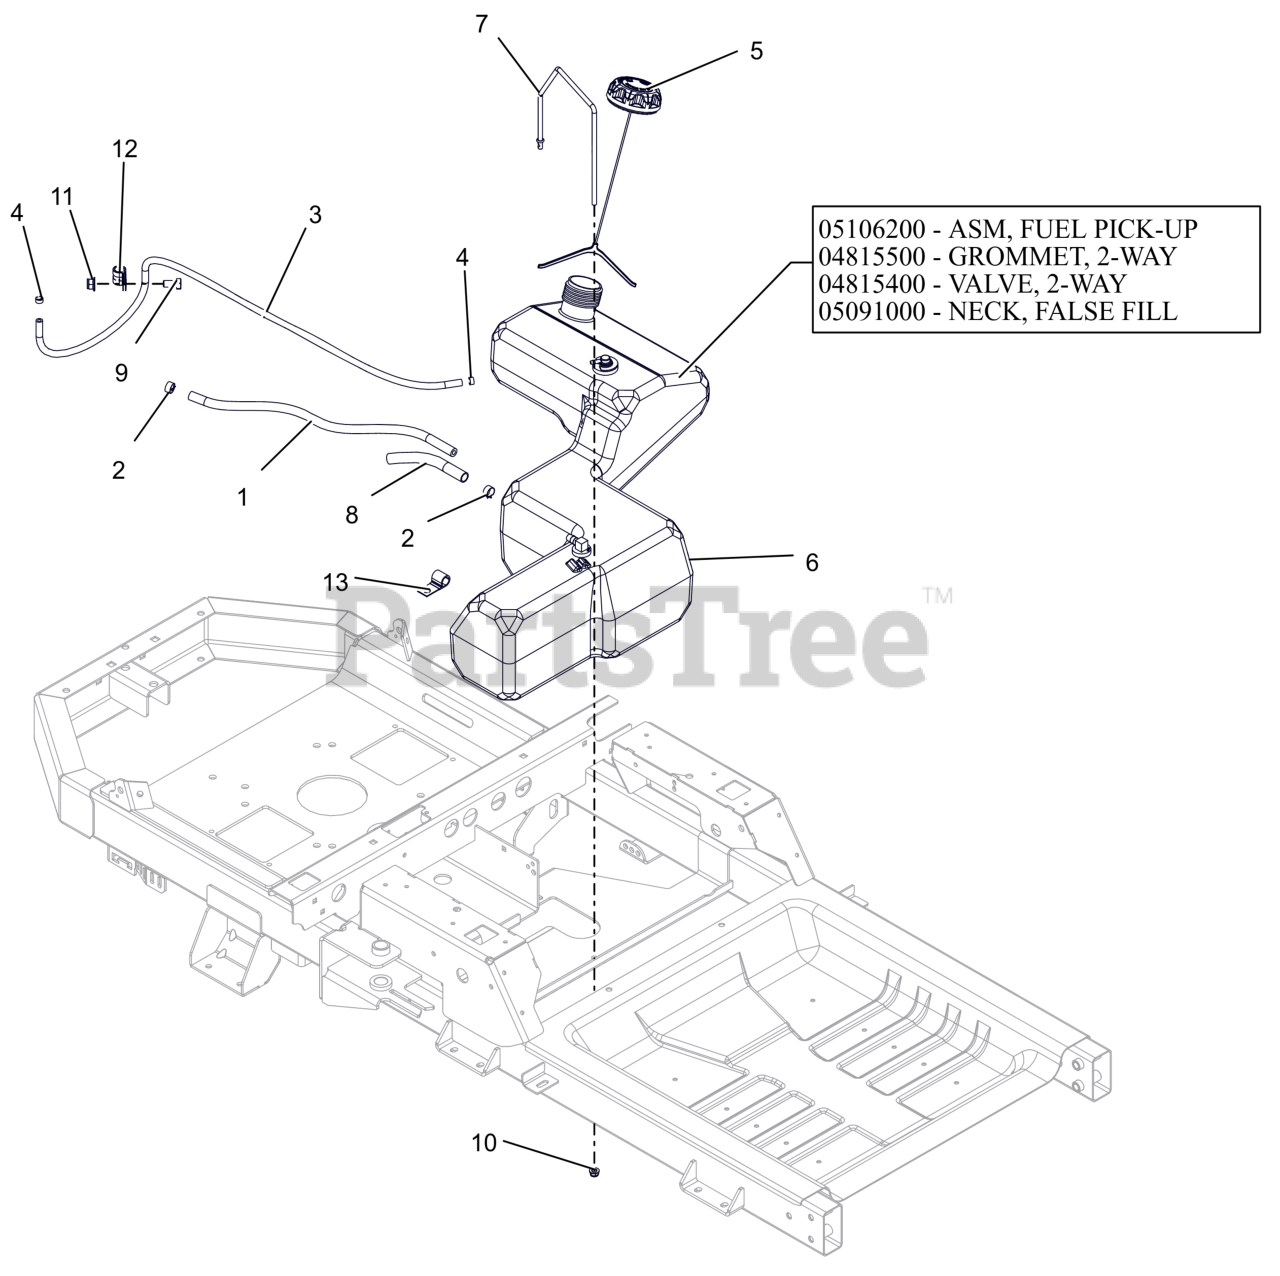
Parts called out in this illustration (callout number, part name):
1	HOSE, .25 LOW-PERM BULK GAS
2	CLAMP, FUEL LINE
3	HOSE, .188 LOW-PERM BULK GAS
4	CLAMP-HOSE, SPRING .188
5	CAP, FUEL VENT-IN 2.25" RATCH.
6	ASSY, FUEL TANK-IKON
6	ASM, IKON FUEL PICK-UP
6	GROMMET, 2-WAY
6	VALVE, 2-WAY
6	NECK, FALSE FILL-2017 IKON
7	BRKT, FUEL TANK HOLD DOWN
8	WRAP, ANTIABRASION .5X.064WALL
9	@BLT-HEX .38-16X.75 GR5 YWZC
10	@NUT-LK-NYL-FLG .25-20 YWZC
11	@NUT-LK-NYL-FLG .38-16 YWZC
12	CLAMP, CUSHIONED STEEL
13	J-CLAMP
